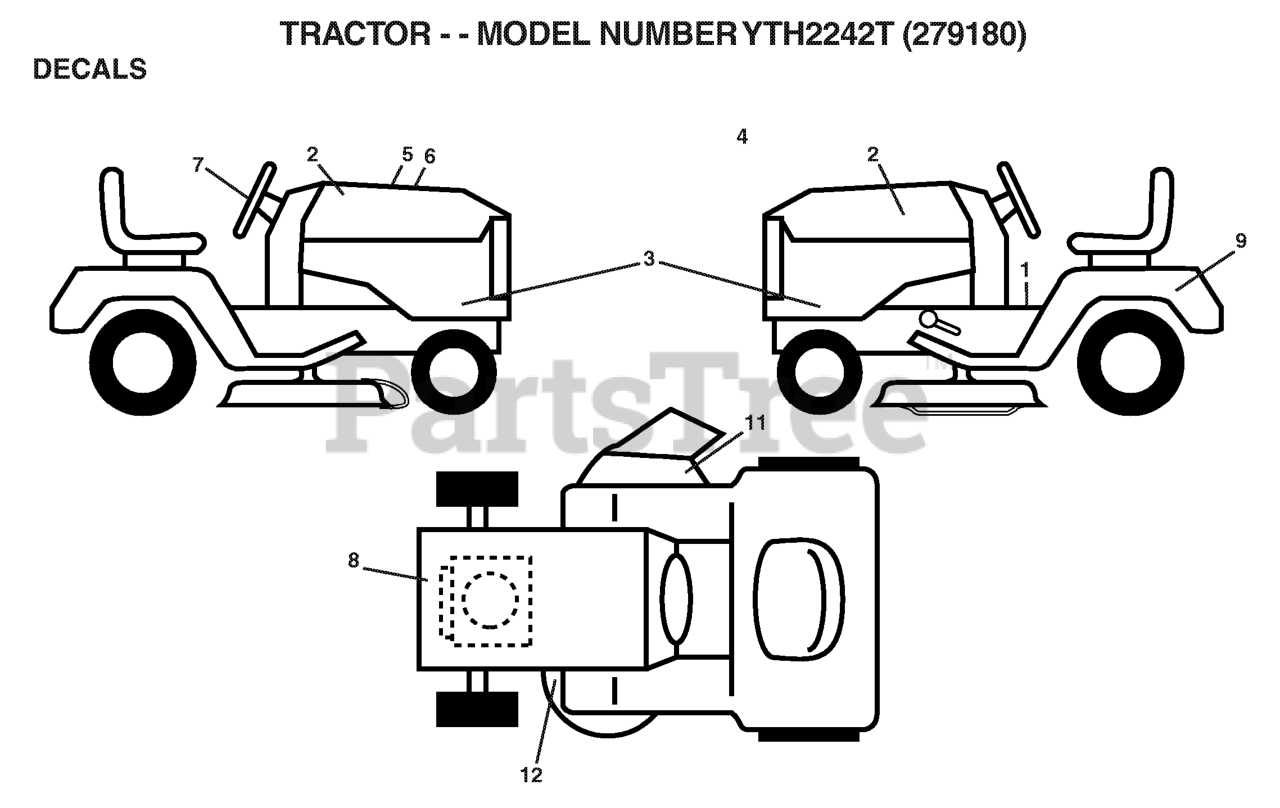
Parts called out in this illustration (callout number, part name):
1	DECAL.FENDER.OPER.TEX.
2	DECAL.HOOD.NAMELOGO.HUSQ
3	DECAL.PANEL.SD.YTH2242
4	DECAL.HOOD.TOP.INSERT.
5	DECAL HOOD CUST. RESP.
6	DECAL.RPL.B&S.22
7	DECAL.WHEEL.STRG.LGN.H
8	DECAL.B&S.22HP#275796
9	DECAL BTRY SYMBOLS
11	DECAL.WARN.KEEP.HAND.AWAY
12	DECAL V BELT SCHEMATIC
